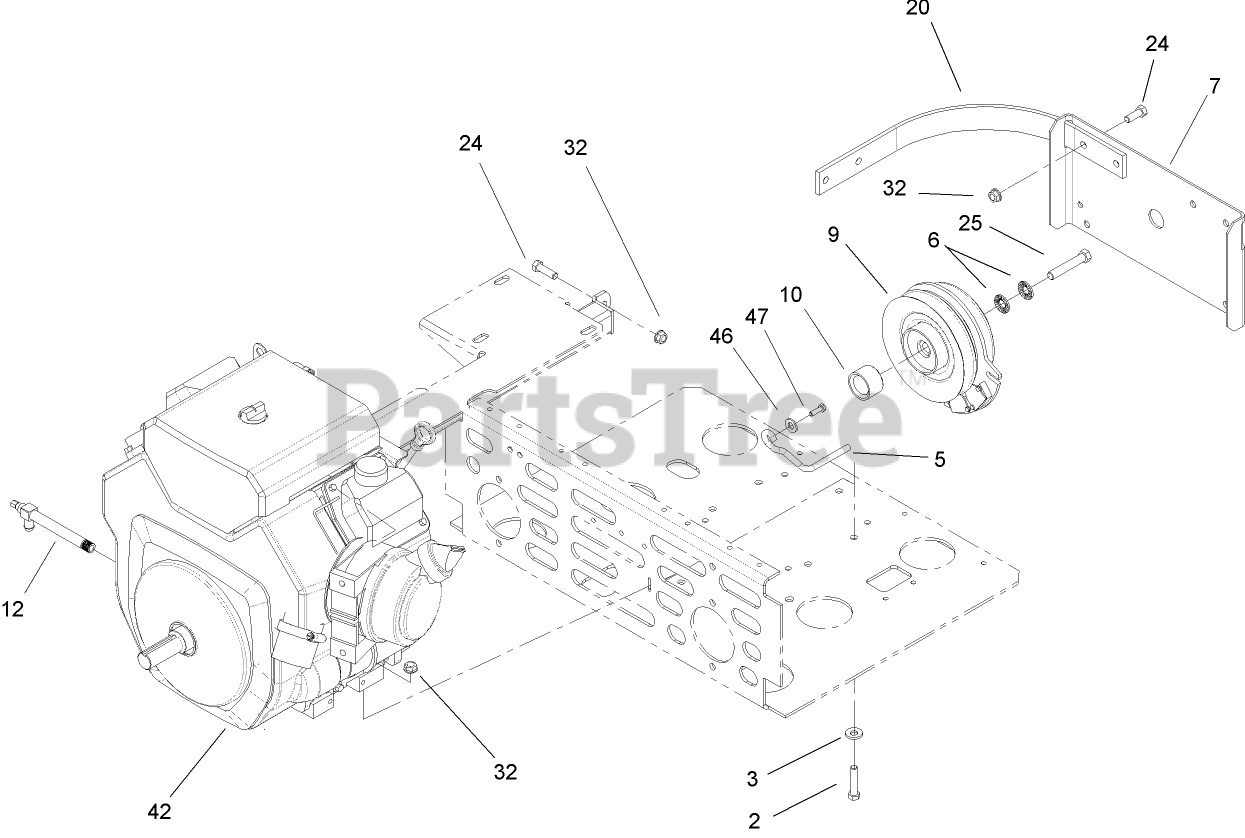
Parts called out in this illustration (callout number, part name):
2	SCREW-HH
3	WASHER-BELLEVILLE
5	ROD-BELT
6	WASHER-SPRING
7	GUARD-CLUTCH
9	CLUTCH
10	SPACER-CLUTCH
12	VALVE-OIL DRAIN, LONG
20	BRACKET-GUARD, TOP
24	SCREW-HH
25	SCREW-HH
32	NUT-HHF, WHIZ
42	ENGINE-KOHLER, CH20 PS-64706 ASM
46	WASHER-FLAT
47	SCREW-HH
